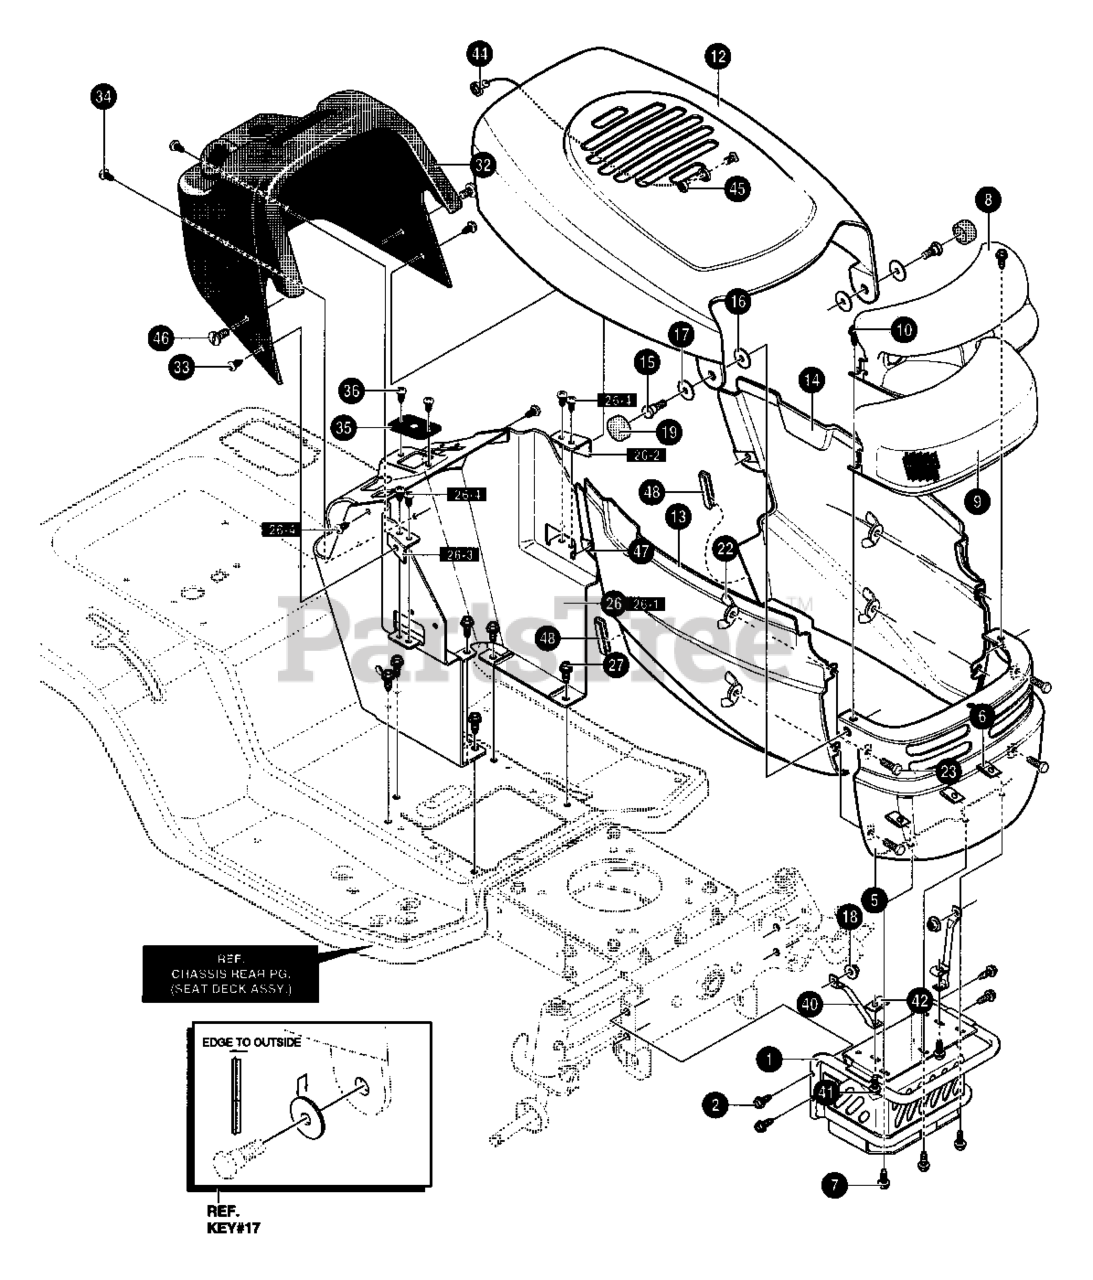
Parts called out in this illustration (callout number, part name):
1	BUMP/GRIL MNT
2	SCREW 5/16-18X1.38
6	NUT, "J" TINNERMAN
7	SCREW 1/4-20X.63
8	REFLECTOR
10	SCREW, 1/4-14X.50
12	ASSEMBLY, HOOD
13	PANEL, SIDE RH
14	PANEL, SIDE LH
16	WASHER, PLASTIC
17	PIVOT BASE
18	NUT, 3/8-16
19	CAP, PIVOT
22	NUT, WING 1/4-20
23	SCREW 1/4-20X1.25
26	CONSOLE ASSY
26-1	CONSOLE, DASH
26-2	BRACKET, LH
26-3	BRACKET, RH
26-4	SCREW, 10-24X.5
27	SCREW 5/16-18
33	SCREW 10-24X.5
34	SCREW 10-24X.5
35	STEERING BEARING
36	SCREW, 1/4-14X.5
40	STRUT, GRILLE
41	SCREW 1/4-20X.63
42	SPEED NUT
44	LANYARD, HOOD
45	NUT, 1/4-20
46	SCREW 1/4-20X.63
47	NUT, "J" TINNERMAN
48	TRIM
